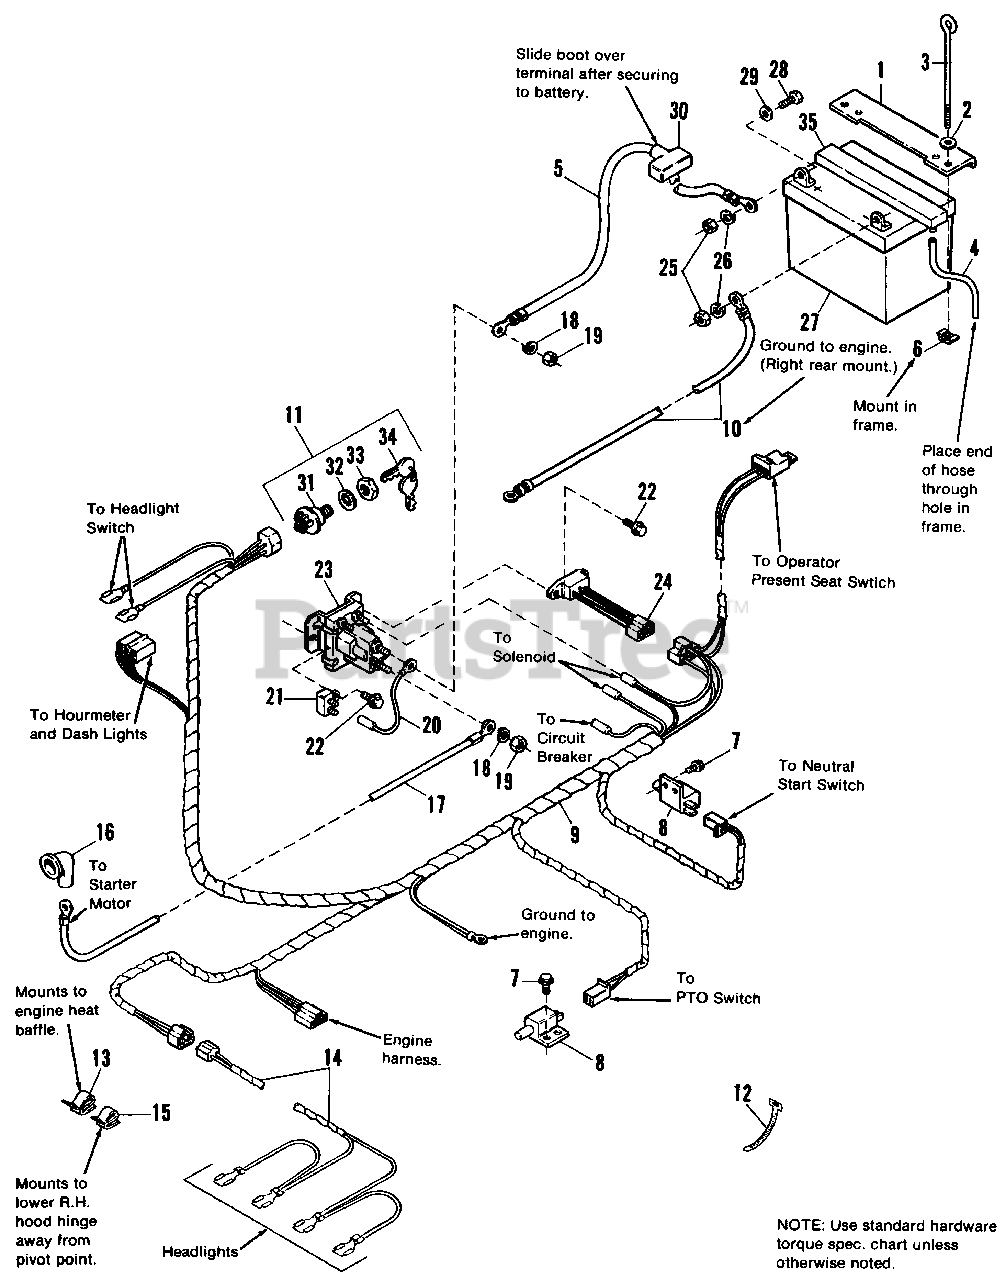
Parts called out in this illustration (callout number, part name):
1	HOLD DOWN, Battery
2	WASHER, 1/4
3	ROD, Battery Hold Down
4	HOSE, Drain, Battery
5	CABLE, Ground
6	NUT, Retainer, 1/4-20
7	SCREW, Taptite, #10-24 x 1/2
8	SWITCH, PTO and Neutral
9	HARNESS, Wiring
10	CABLE, Ground to Engine
11	SWITCH, Ignition (Incl. Ref. Nos. 31, 32, 33 & 34)
13	CLIP, Wire
14	WIRE ASSY., Headlights
16	COVER, Terminal
18	LOCKWASHER, 5/16
19	NUT, Hex, 5/16-24
21	CIRCUIT BREAKER
22	SCREW, Taptite, 1/4-20 x 5/8
23	SOLENOID
24	MODULE, DSI Interlock
25	NUT, Hex, 1/4-20
26	LOCKWASHER, 1/4
27	BATTERY, 39 Amp.
28	CAPSCREW, Hex Hd.,1/4-20 x 3/4
29	WASHER, 1/4 I.D.
30	BOOT, Insulator
32	LOCKWASHER, Internal, 5/8
33	NUT, Hex, 5/8-32
35	VENT, Battery
